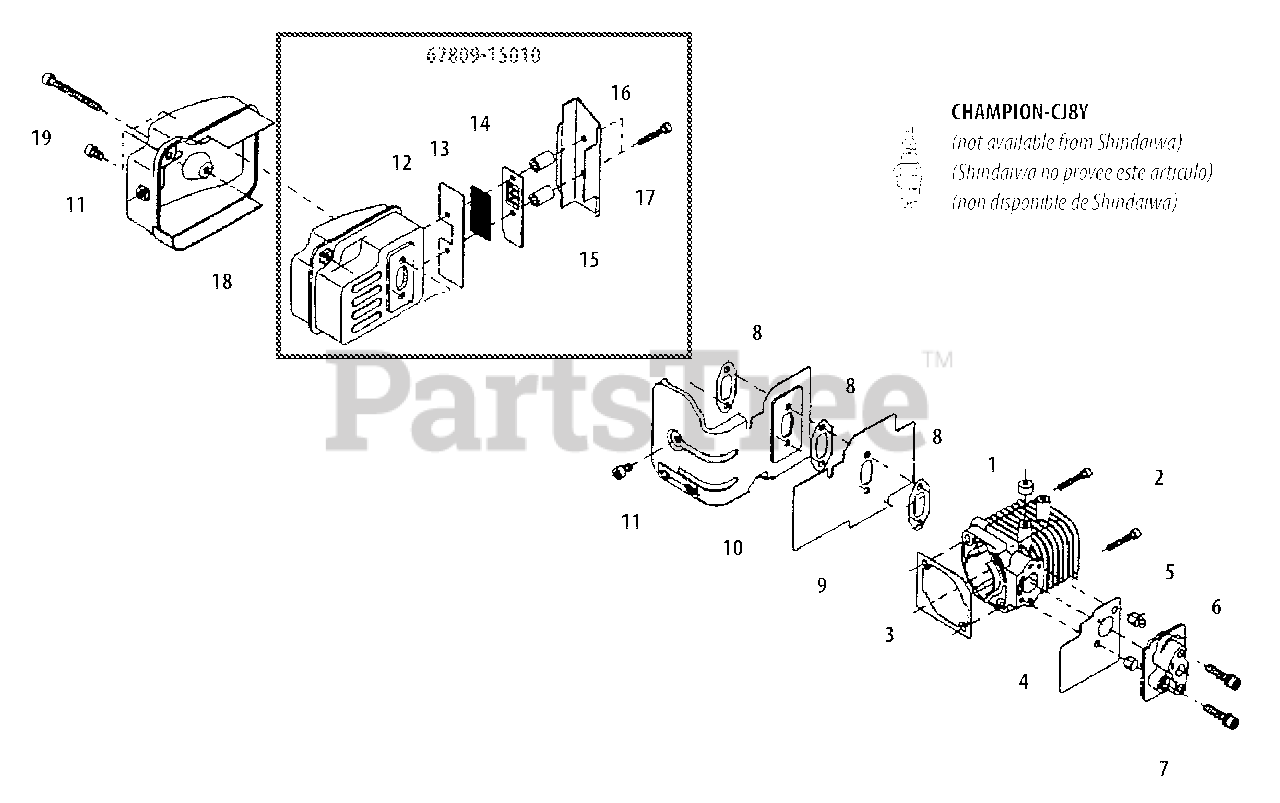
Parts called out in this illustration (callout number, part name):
1	CYLINDER
2	BOLT 5×25
3	GASKET, CYLINDER
4	GASKET
5	NUT M5×6.3
6	INSULATOR
7	BOLT SS M5×30
8	GASKET, EXHAUST
9	SHIELD, EXHAUST
10	GASKET, EXHAUST
11	BOLT 5×8
12	PLATE
13	SCREEN, SPARK ARRESTER
14	OUTLET, EXHAUST
15	SPACER
16	DEFLECTOR
18	COVER, MUFFLER
19	BOLT M5×65
62809-15010	MUFFLER ASSY
